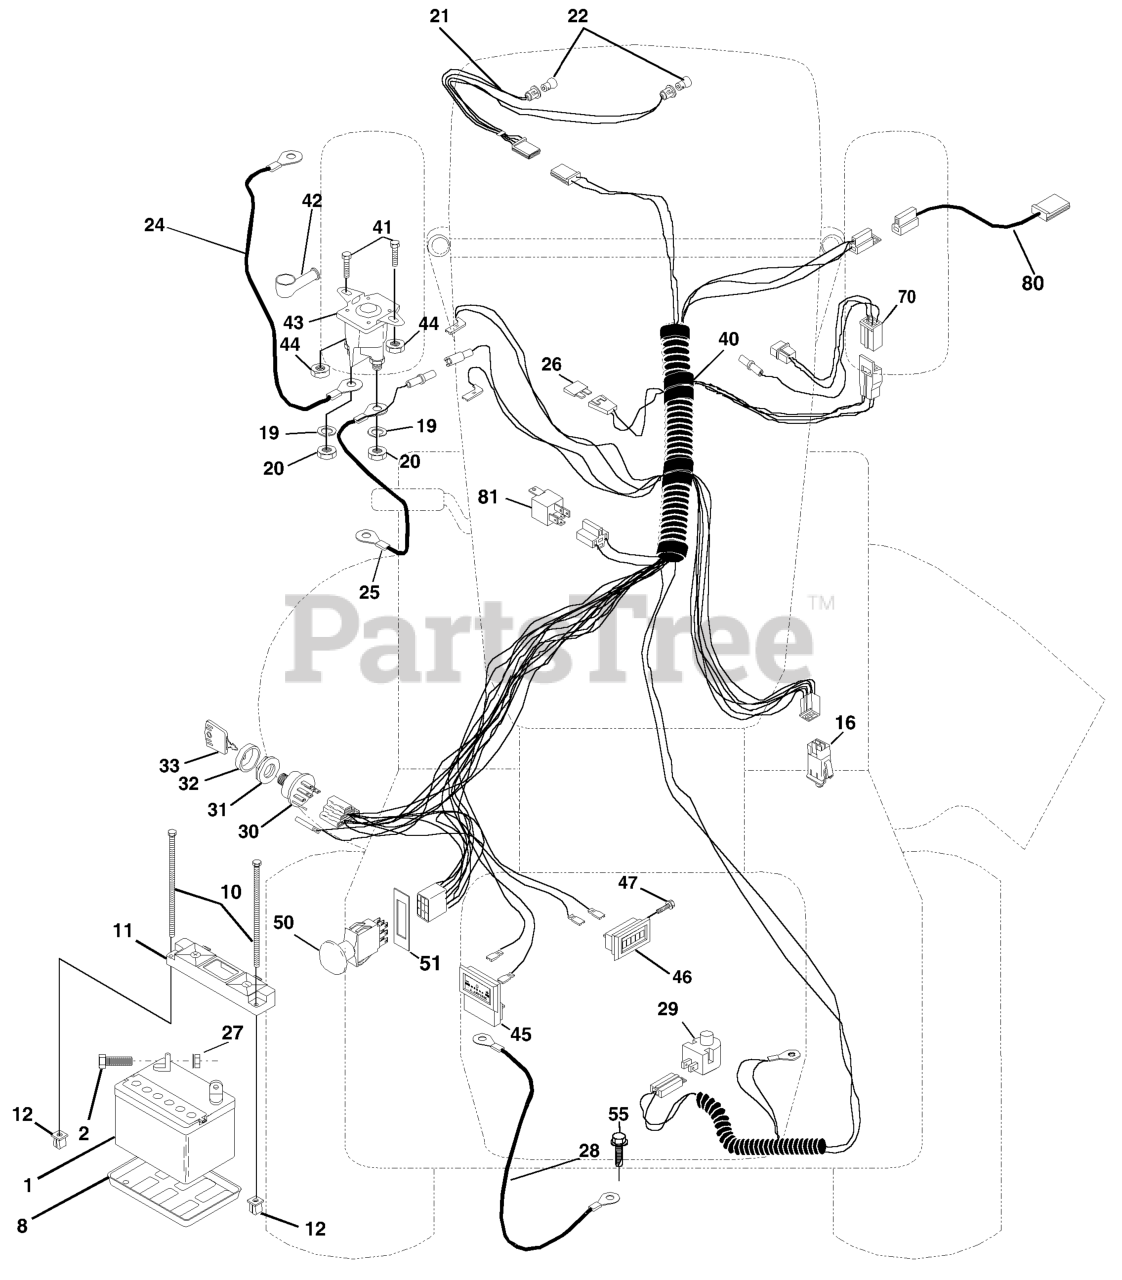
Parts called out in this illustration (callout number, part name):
1	BATTERY 12V .35 AMP
2	BOLT.HEX.1/4.X.3/4.DICHROMATE
8	BATTERY TRAY T
10	BOLT 1/4-20 X 7.5
11	BATTERY HOLDDOWN FRONT MOUNT
12	NUT, PUSH NYLON 1/4" BATTERY
16	SWITCH INTERLOCK
19	LOCKWASHER
20	NUT
24	BATTERY CABLE GT
25	CABLE BATTERY 6 GA 22" W/16W
26	FUSE 15 AMP
27	NUT
28	CABLE GROUND 6 GA 21" 90T BLK
29	PLUNGER SWITCH (COLOR:OLIVE)
30	SWITCH.IGNITION.4.POSITION
31	NUT IGNITION
32	COVER SWITCH KEY
33	KEY.MOLDED.GENERIC
40	IGNITION HARNESS
41	BOLT
42	TERMINAL COVER
43	SOLINOID
44	Nut, Hex, Keps 1/4-20 UNC
46	HOUR METER T
47	Screw 10-24 x 1/2 Black
50	SWITCH PTO 3 PDT
51	FRAME RETAINING RING
55	Screw, Thdrol 5/16-18 x 1/2 TYT
70	CABLE ASS[
80	HARNESS, CLUTCH
81	RELAY.ASSY.T
